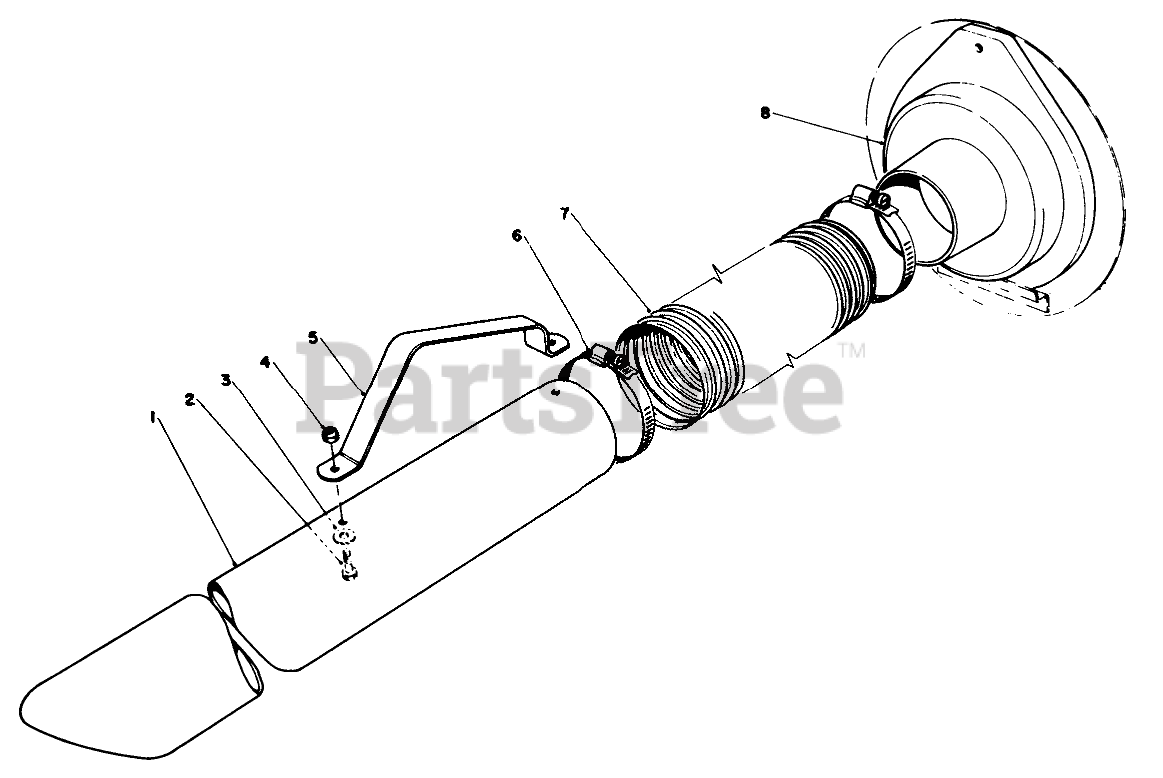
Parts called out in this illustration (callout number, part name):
1	NOZZLE
2	SCREW-HH
3	SPECIAL WASHER
4	NUT-KEPS
5	NOZZLE HANDLE
6	CLAMP
7	VACUUM HOSE
8	ADAPTOR HOSE TO HSG
